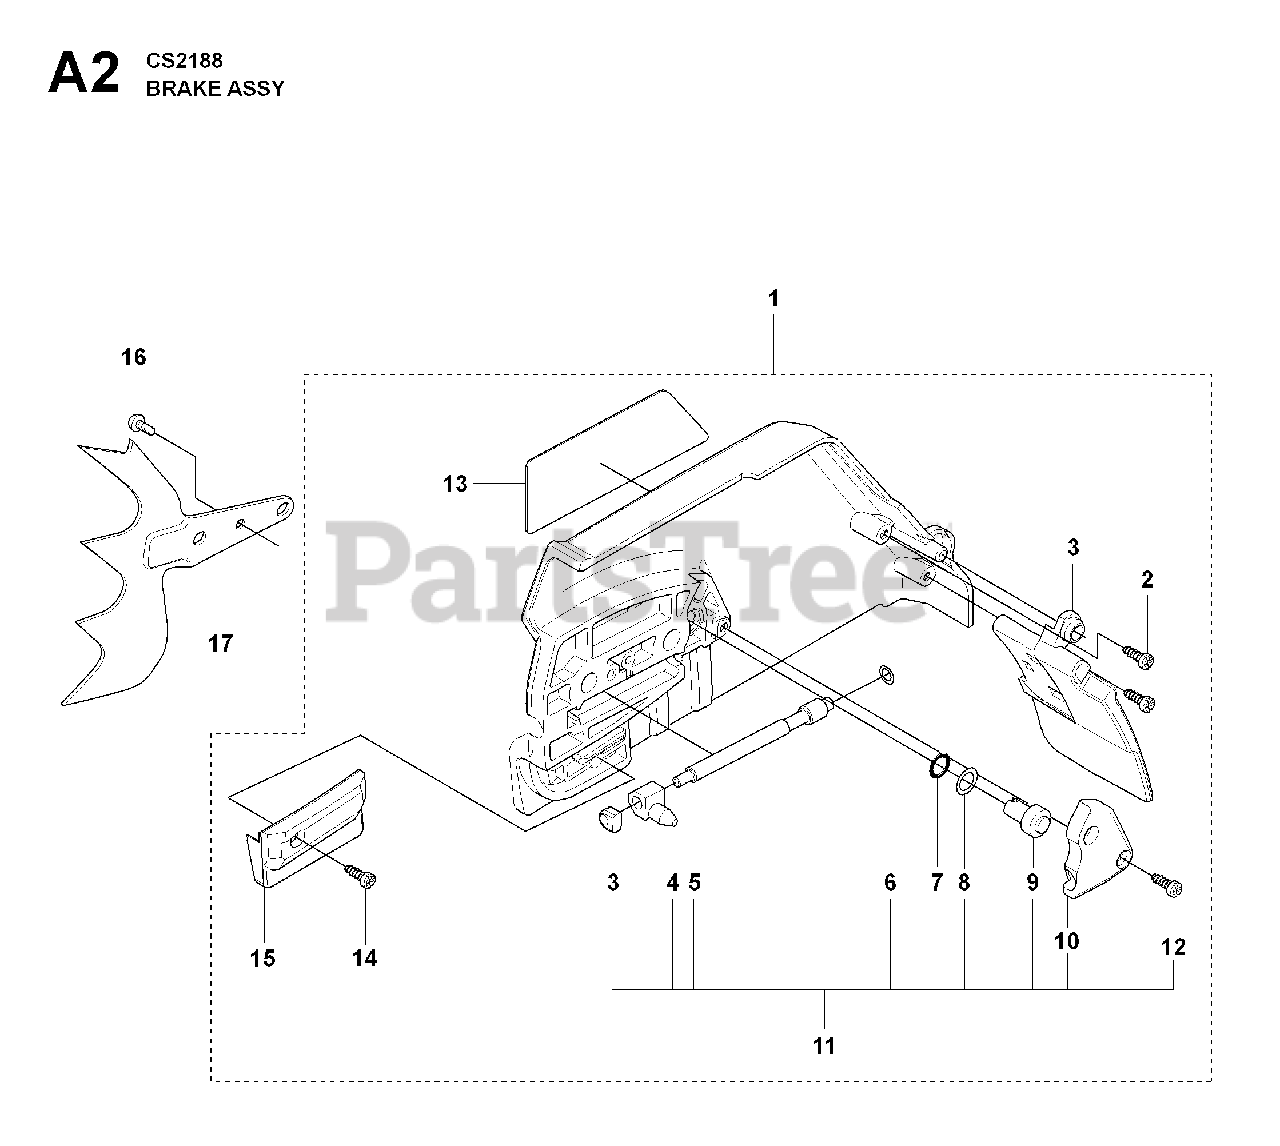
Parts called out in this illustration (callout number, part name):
1	CLUTCH COVER
2	SCREW
3	PROTECTOR
4	COUPLING
5	ADJUSTER
6	WASHER
7	O-RING
8	WASHER
9	RP ADJUSTER
10	COVER
11	KIT-CHAIN TENSIONER
12	SCREW
13	DECAL
14	SCREW
15	CHAIN GUIDE
17	FELLING DOG
